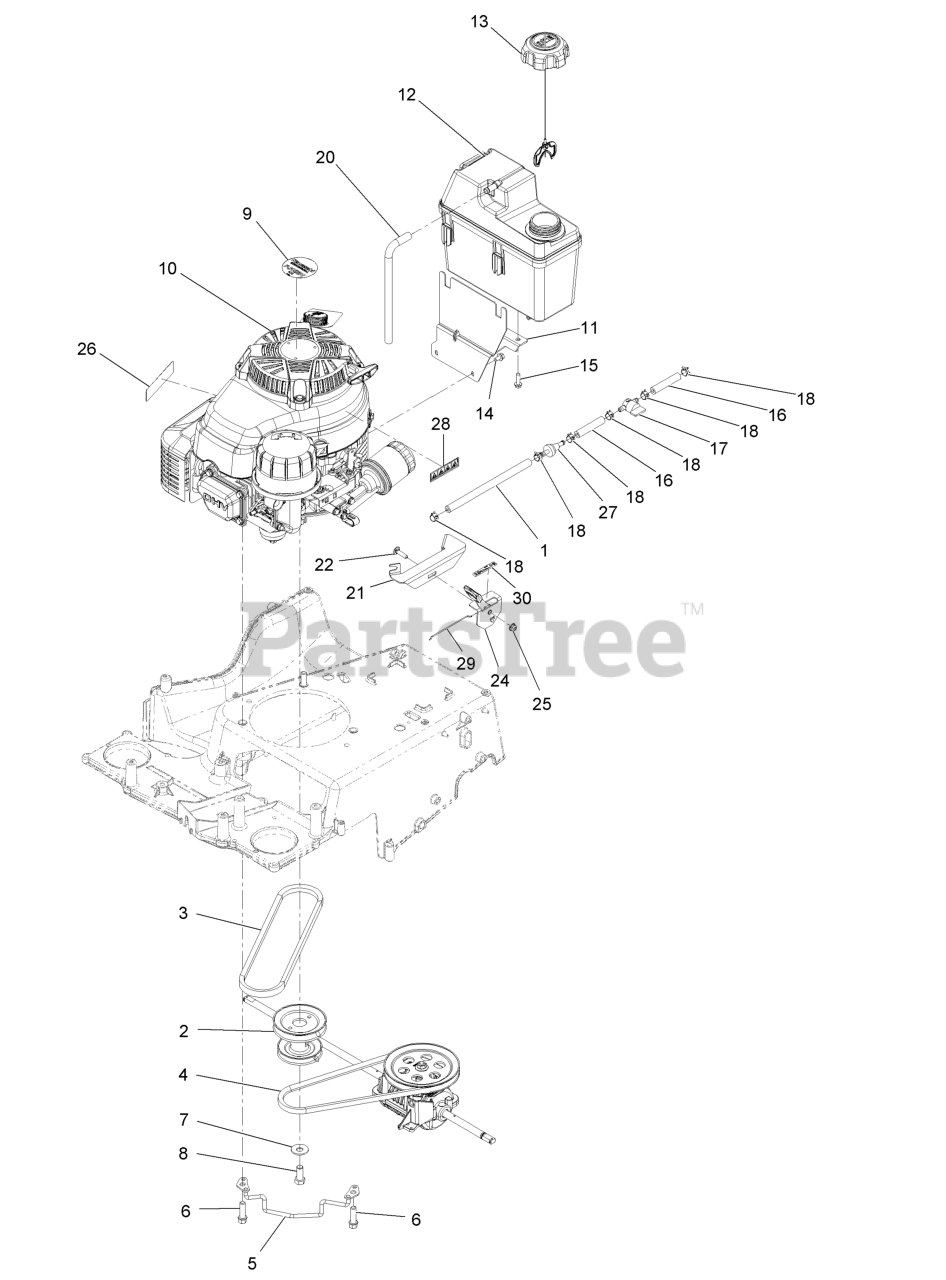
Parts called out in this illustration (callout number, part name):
1	Hose-Fuel
2	Pulley-Engine
4	Belt
5	Guide-Belt
6	Screw-HWH 3/8-16 X 1 1/4 Taptite
7	Washer-Spring Disc
8	Screw-HH 7/16-20 X 1
9	Decal-Recoil
11	Mount-Tank
12	Tank-Fuel
13	Cap-Fuel
14	Screw-HWH
15	Screw-HWH 1/4-10 X .82 Plastite
16	Hose-Fuel Line 2 1/2"
17	Valve-Fuel
18	Clamp-Hose
20	Hose-Vent, Canister
21	Bracket-Mount, Throttle
22	Bolt-Carriage 1/4-20 X 1
24	Control-Throttle
25	Nut-Nyloc 1/4-20 Flg
26	Decal-Arrester, Spark
27	Filter-Fuel
28	Decal-Warning, Engine
29	Wire-Control
30	Decal-Throttle, Choke
